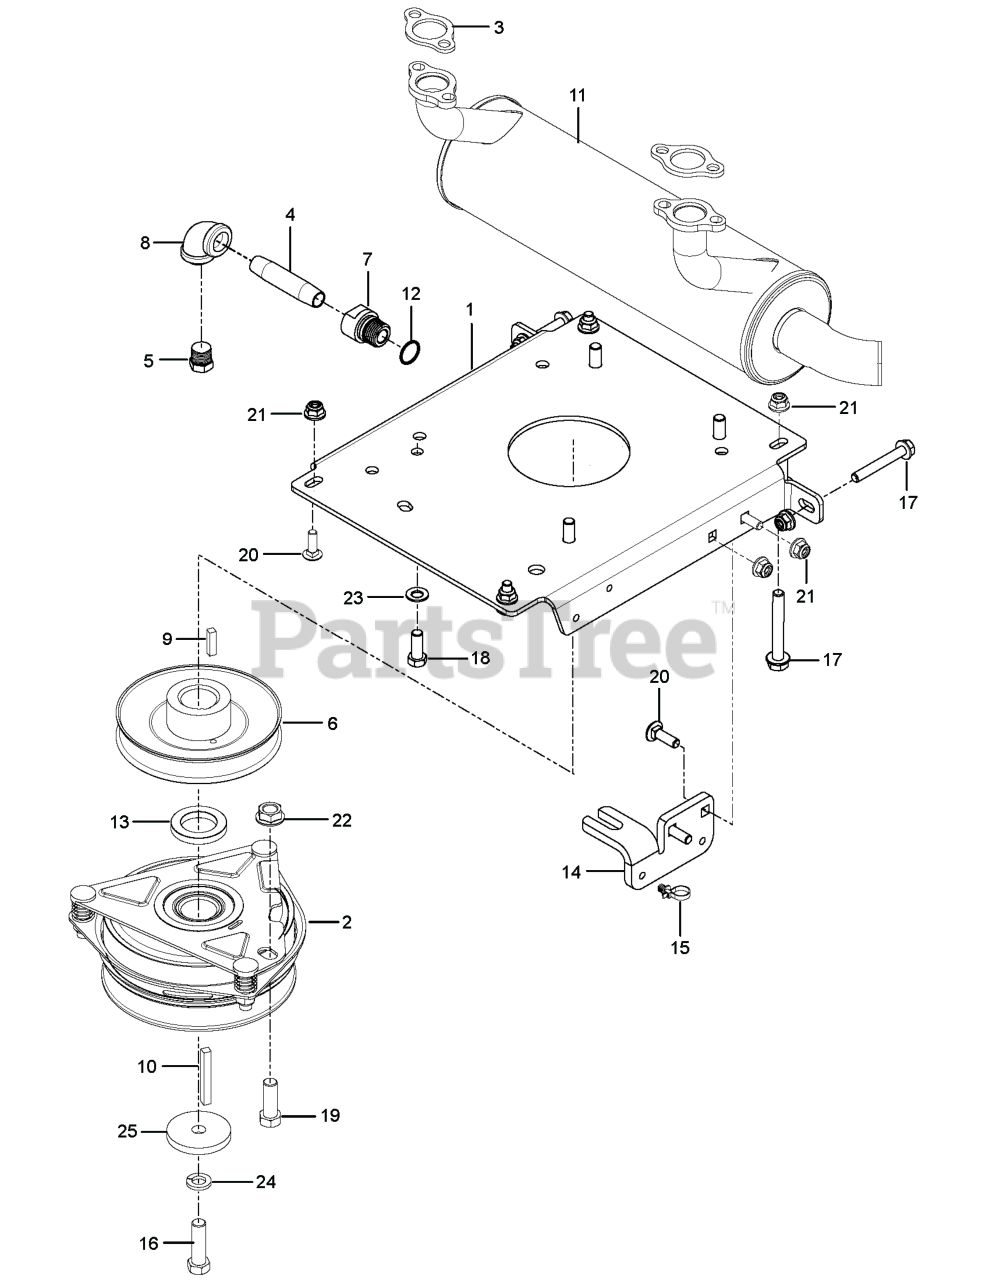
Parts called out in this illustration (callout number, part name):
1	PLATE.PNT.ENGINE.PZ/PZT.EDIP
2	CLUTCH, 150 FT/LBS
3	GASKET.EXHAUST.KAWASAKI
4	PIPE NIPPLE 3/8 X 3
5	PLUG, DRAIN 3/8 NPTF
6	PULLEY, ENGINE
7	ADAPTER, OIL DRAIN
8	90 DEG.ELBOW 3/8NPT
9	KEY 1/4 SQ X 1.0
10	KEY 1/4 SQ X 2
11	MUFFLER, 29HP KAW FX751V-850V
13	SPACER, .25 X 1.135 I.D.
14	STOP, CLUTCH, OGURA
15	TIE WRAP, 8-3/8", W/CLIP
16	CLUTCH BOLT7/16-20X1.5GR5.96HR
17	HHFS 5/16-18 X 2.25 GD 5
18	HCS 3/8-16X1.GRD.5.ZD
19	HCS 7/16-14 X 1-1/4 GR 5 ZD
20	RHSNB 5/16C X 1
21	5/16-18 NYLOC FLANGE NUT
22	NUT 7/16C WHIZ
23	WASHER, 3/8 DISC SPRING SPEC
24	WASHER 7/16 LOCK
25	BLADE WASHER
